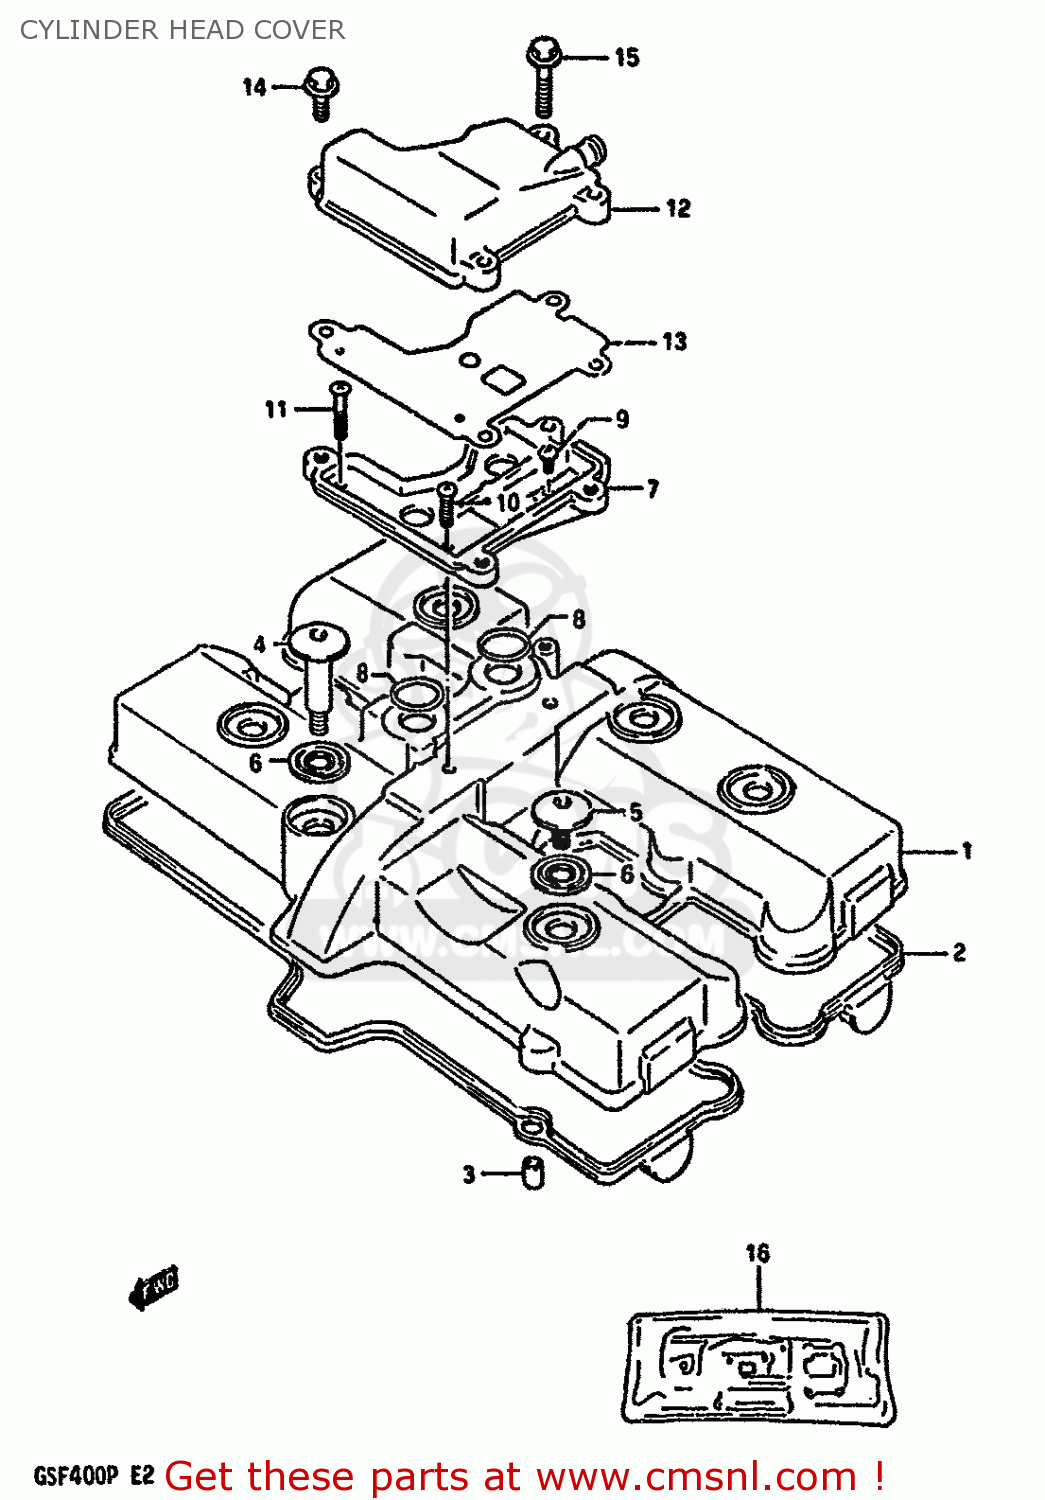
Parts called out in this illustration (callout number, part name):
1	COVER,CYLINDER HEAD
2	GASKET,CYLINDER HEAD COVER (NAS)
3	PIN(6.2X8X11)
4	BOLT(7X37)
5	BOLT(7X18.5)
6	WASHER(10.6X25.5X2.3)
7	COVER,BREATHER,LOWER
8	O RING(D:2.4,ID:19)
9	SCREW 5X10
10	SCREW
11	SCREW
12	COVER,BREATHER,UPPER
13	GASKET,BREATHER COVER (NAS)
14	BOLT 6X20
15	BOLT 6X35
16	GASKET SET
